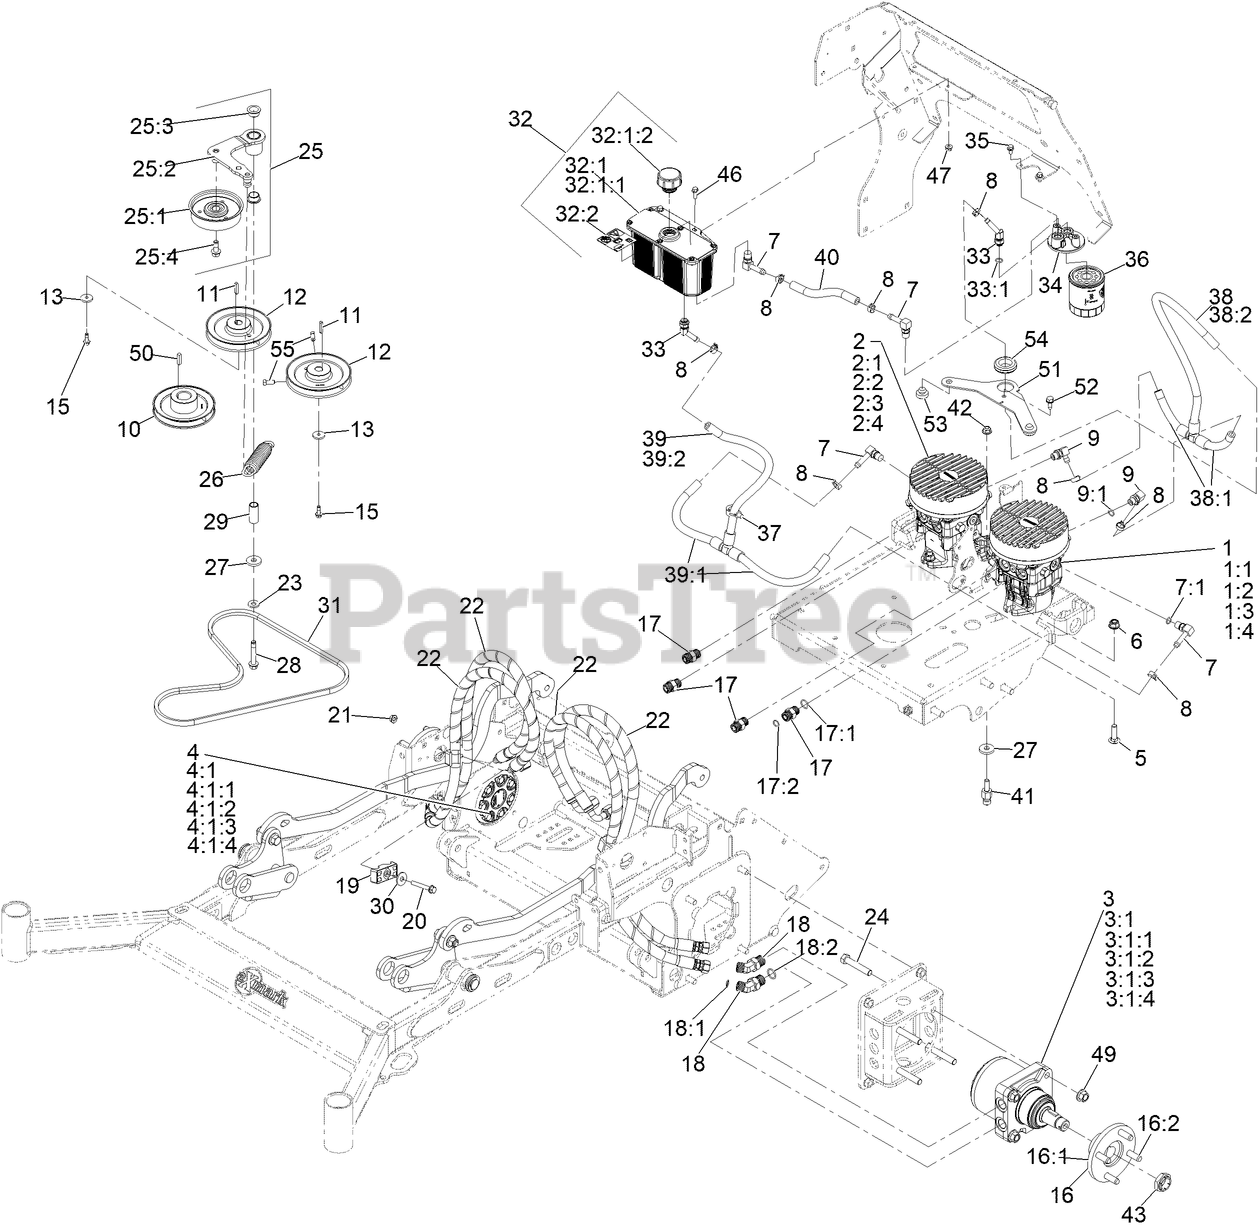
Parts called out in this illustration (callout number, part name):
1	PUMP-12CC LT W/SHOCK VALVE
1:1	KIT, 10CC/12CC PUMP KIT
1:2	SEAL OVERHAUL KIT
1:3	GUARD-PUMP
1:4	PUMP-COOLING
2	PUMP-12CC RT W/SHOCK VALVE
2:1	KIT, 10CC/12CC PUMP KIT
2:2	SEAL OVERHAUL KIT
2:3	GUARD-PUMP
2:4	PUMP-COOLING
3	MOTOR, TL240 LH
3:1	SEAL KIT
4	MOTOR, TL240 RH
4:1	SEAL KIT
5	BOLT-CARR
6	NUT-HF, NI
7	FITTING-ELBOW, 90
7:1	O-RING
8	CLAMP-HOSE
9	FITTING-90 DEG
9:1	O-RING
10	SHEAVE-PUMP, DRIVE
11	KEY, 5MM X 5MM X 29MM
12	SHEAVE-PUMP
13	WASHER-1.00 OD X .25 ID
15	SCREW-HHF
16	WHEEL HUB / STUD ASM
16:1	HUB-WHEEL
16:2	STUD-TYPE, DRIVE
17	FITTING-STRAIGHT
17:1	O-RING
17:2	O-RING
18	Fitting-HYD, 45 DEG
18:1	O-RING
18:2	O-RING
19	CLAMP-TUBE
20	CLAMP-TUBE
21	NUT-HF, NI
22	HOSE ASM-HYD HP
23	WASHER-BELLEVILLE
24	SCREW-HH
25	ASM-PUMP IDLER
25:1	PULLEY-IDLER 4.15 FLAT SINGLE FLNG
25:2	ASM-PUMP IDLER ARM
25:3	BUSHING-FLANGE
25:4	SCREW-HFH
26	SPRING, EXTENSION
28	SCREW-HHF
29	PIVOT, IDLER
31	BELT- COG A 54
32:1	Reservoir-HYD
32:1:1	Cap-Reservoir, HYD
32:2	DECAL-WARNING
33	FITTING-BARBED, 45 DEG
33:1	O-RING
34	HEAD-FILTER
35	SCREW-HHF
36	FILTER-25 MICRON, BI-DIRECTIONAL
37	CLIP-TIE
38	ASM-HYDRAULIC LO-PRES
38:1	HOSE, LP HYDRO
38:2	HOSE, LP HYDRO
39	ASM-HYDRAULIC LO-PRES
39:1	HOSE, LP HYDRO
39:2	HOSE, LP HYDRO
40	HOSE, LP HYDRO
41	PIN-SPRING, ANCHOR
42	NUT-HF, NI
43	LOCKNUT
46	SCREW-HHF
47	NUT-HHF
49	Nut-Lock 1/2-13
51	PLATE-HOLD DOWN
52	SCREW-THD ROLL, HWH
53	BUMPER-RUBBER
54	GROMMET
55	SCREW-SET, SQH
